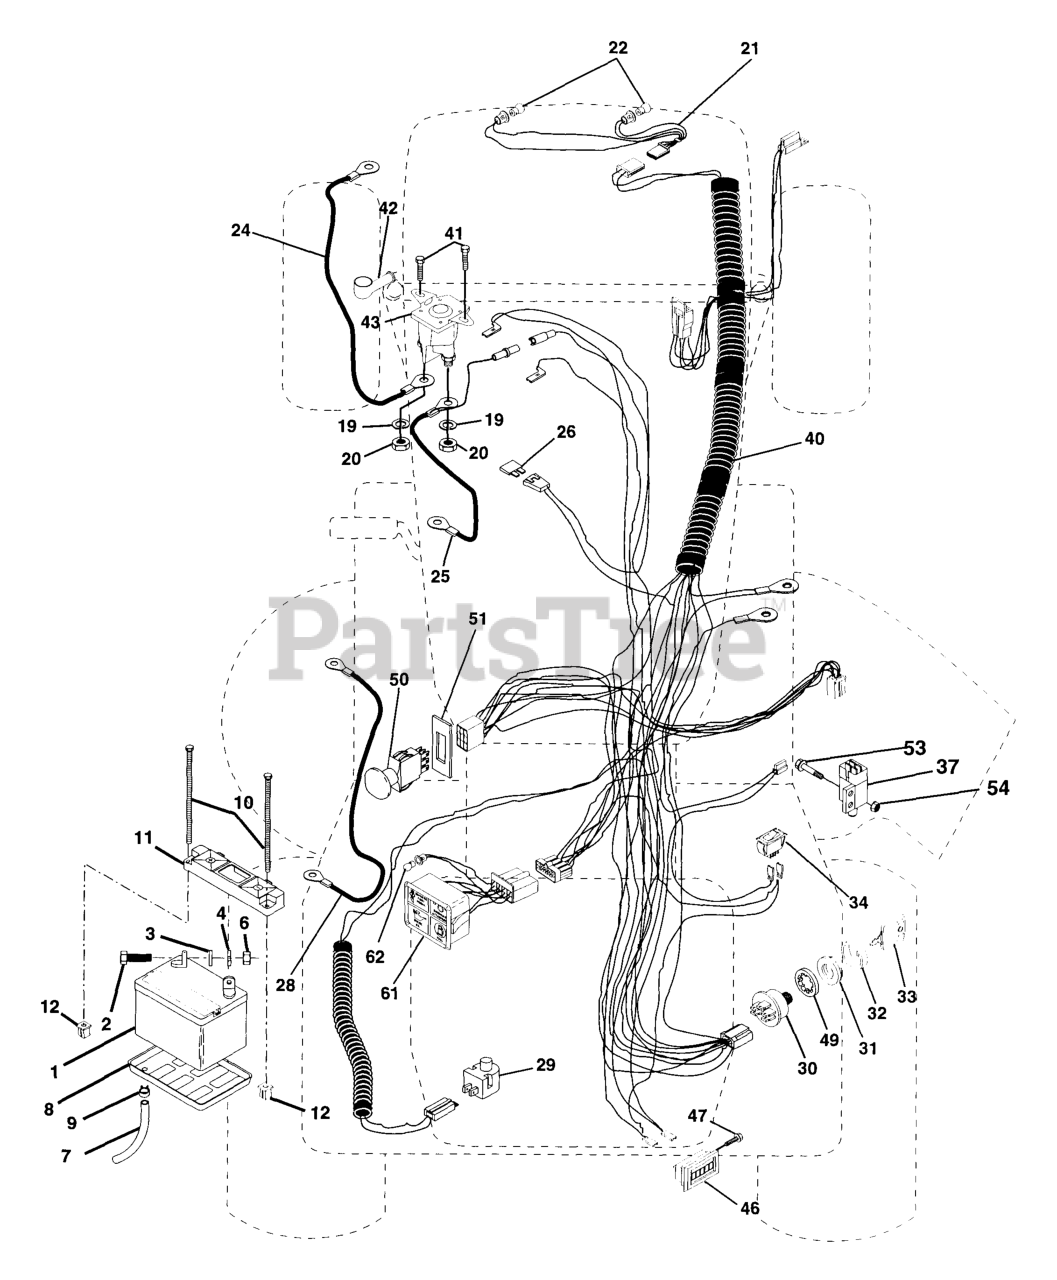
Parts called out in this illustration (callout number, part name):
1	BATTERY 12V .35 AMP
2	BOLT.HEX.1/4.X.3/4.DICHROMATE
3	LOCKWASHER
4	WASHER
6	NUT
7	PLASTIC TUBE
8	BATTERY TRAY T
9	HOSE CLAMP T
10	BOLT 1/4-20 X 7.5
11	HOLDDOWN, BATTERY, DASH MOUNT
12	NUT, PUSH NYLON 1/4" BATTERY
19	LOCKWASHER
20	NUT
21	HARNESS LIGHT SOCKET
24	CABLE, STARTER
25	CABLE, BATTERY
28	CABLE, GROUND
29	RP.SWITCH.PLUNGER.NC.GRAY
30	IGNITION SWITCH
31	NUT, IGNITION
32	COVER SWITCH KEY
33	KEY MLD GEN DELTA
37	SWITCH INTERLOCKT
40	HARNESS, IGNITION
41	SCREW
42	TERMINAL COVER
43	SOLINOID
46	HOUR METER T
47	Screw #10-24 x 1/2
49	Washer, Lock Internal Tooth 5/8
50	SWITCH-PTO
51	FRAME RETAINING RING
61	LIGHT PACKAGE
62	BULB LIGHT T
